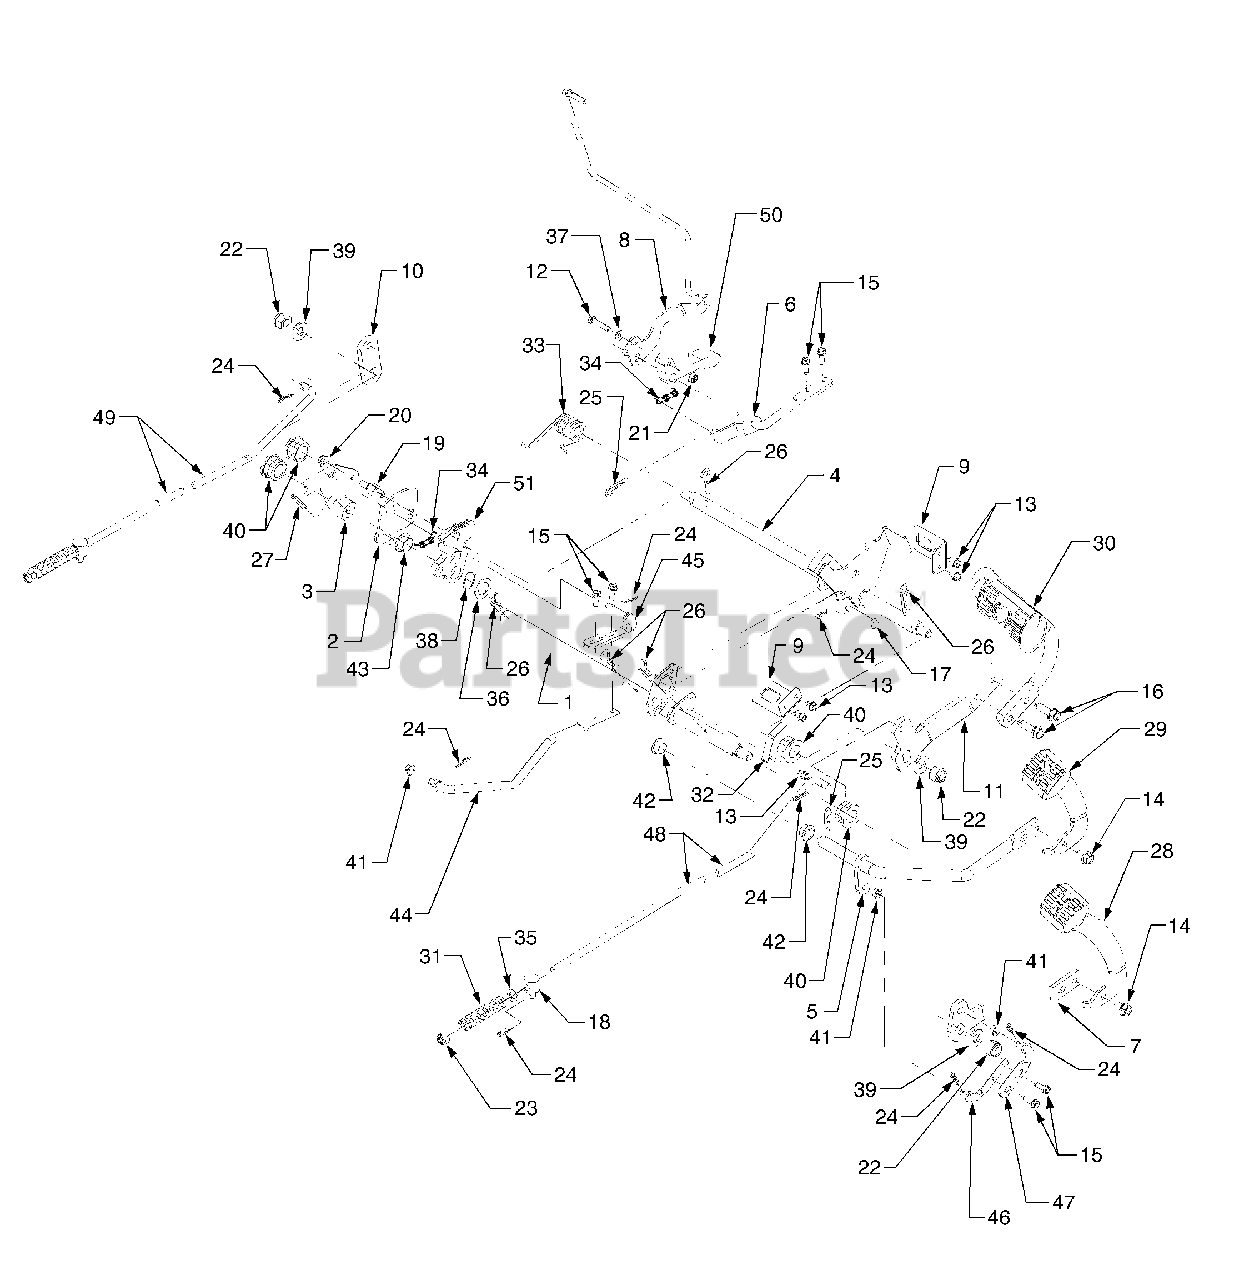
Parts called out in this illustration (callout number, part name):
1	Shaft Assembly, Pedal
2	Plate, Disengagement
4	Shaft Assembly, Brake
5	Shaft Assembly, Reverse
6	Rod Assembly, Cruise
7	Link, Pedal Mounting
8	Bracket, Rod Adjust
9	Bracket, Switch
10	Lever, Brake
11	Link, Brake Pedal
12	Screw, Hex Cap, 1/4-20 x 1.25 GR5
13	Screw, Hex Wash. Hd. Tapp 1/4-20 x .5
14	Screw, Hex Wash. Hd. Tapp 3/8-16 x .75
15	Screw, Hex Wash. Hd. Tapp 1/4-20 x .75
16	Screw, Hex Wash. Hd. Tapp 3/8-16 x 1.25
17	Pin, Clevis, 3/8 x 2.015
18	Ferrule, Adjust.
19	Stud, Actuator
20	Nut, Hex Flange Lock, 5/16-18
21	Nut, Hex Flange Lock, 1/4-20
22	Nut, Hex Insert Lock, 1/2-20
23	Nut, Hex Lock, 3/8-24
24	Pin, Internal Cotter
25	Pin, Internal Cotter
26	Pin, Internal Cotter
27	Pin, Spiral Spring, .25 x 1.5
28	Pedal, Forward
29	Pedal, Reverse
30	Pedal, Brake
31	Spring, Compression
32	Spring, No Cut Reverse
33	Spring, Torsion
34	Spring, Extension, .380 OD x 1.44
35	Washer, Flat, .406 x .75 x .063
36	Washer, Flat, .79 x 1.24 x .060
37	Washer, Flat, .25 x .62
38	Washer, Wave, .785 x 1.0 x .012
39	Washer, Flat, .531 x 1.06 x .134
40	Bearing, Hex Flange
41	Bearing, Flange
42	Bearing, Flange
43	Bearing, Flange
44	Rod, Rear Control
45	Rod, Front Control
46	Rod, Rear Connecting
47	Rod, Front Connecting
48	Rod, Brake RH
49	Rod, Brake LH
50	Cruise Latch
51	Plate, Cruise
